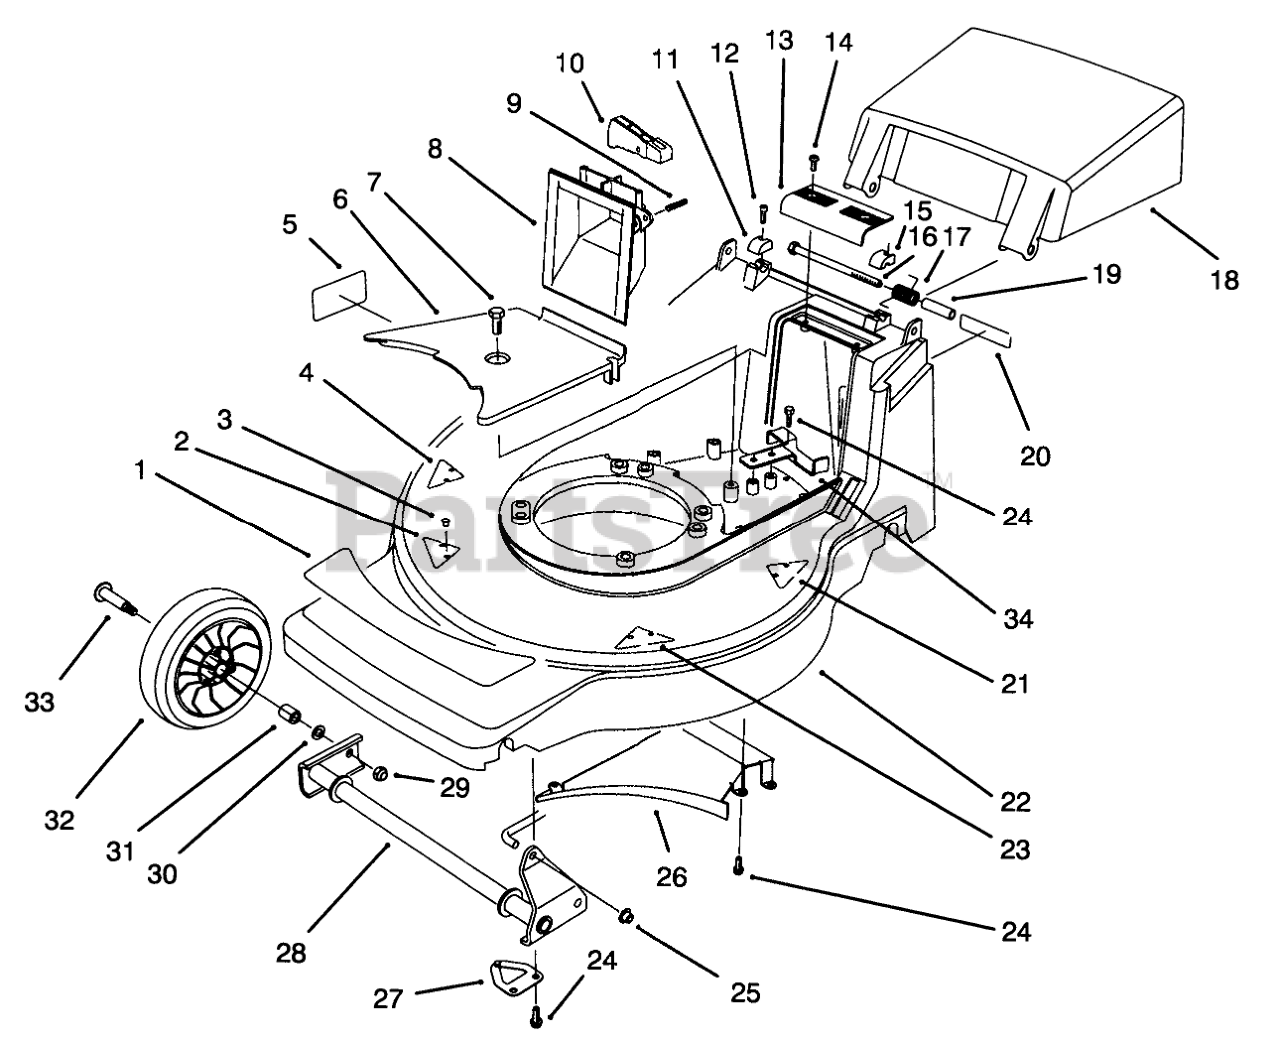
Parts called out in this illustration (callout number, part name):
1	DECAL - DECK
2	KICKER
3	SCREW-PPH
4	KICKER
5	DECAL - DIN/DANGER
6	BELT COVER
7	SCREW-HWHTF
8	GRIP - LOWER
9	PIN-SPIRAL
10	TRIGGER - HOC
11	CAP-HINGE BOLT, RH
12	SCREW-HSH
13	GRIP-UPPER
14	SCREW-PPH, PLASTITE
15	CAP-HINGE BOLT, LH
16	SCREW-HH
17	SPRING-DOOR
18	Door Discharge
19	SPACER-DOOR
20	DECAL FRENCH REGUL.
21	KICKER
22	Housing-Deck (Incl. Ref.#2-5,20,21,&23)
23	KICKER
24	SCREW-HWH
25	NUT-PUSH
26	Ramp-Discharge
27	SHAFT RETAINER ASM
28	FRONT PIVOT WA
29	NUT-HEX
30	WASHER
32	7 " WHEEL/TIRE ASM
33	BOLT-WHEEL
34	REAR BELT GUIDE
